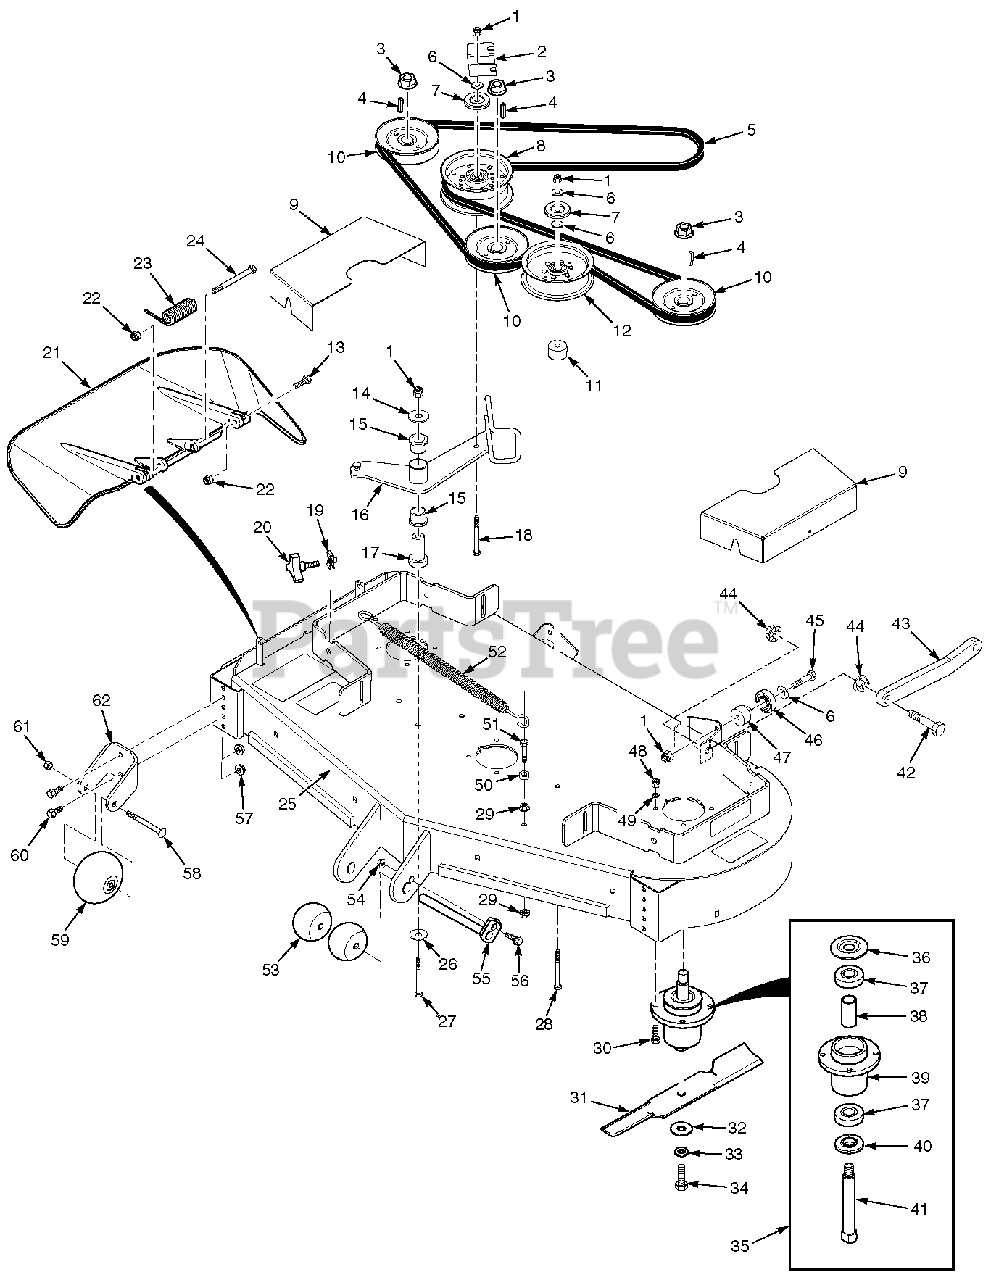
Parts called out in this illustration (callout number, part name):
1	Nut, Elastic Stop 3/8-16
2	Bracket, Belt Guide
3	Nut, 3/4-16 Spiral Lock
4	Key, 1/4 x 1/4 x 1-1/4"
5	Belt, Cutter Deck
6	Flatwasher, 3/8-.391 x .938 x .105
7	Dust Shield
8	Pulley, 5" Idler
9	Belt Cover
10	Pulley, 5.73" OD - 25mm Bore
11	Spacer
12	Pulley, 5" Idler
13	Bolt, Hex Head 5/16-18 x 1-3/4"
14	Flatwasher, 3/8-.406 x 1-1/2"
15	Bearing
16	Idler Arm
17	Pivot, Idler
18	Bolt, Hex Head 3/8-16 x 3-1/4"
19	U-Nut, 3/8-16
20	Knob w/Stud
21	Discharge Chute Assembly
22	Nut, Elastic Stop 5/16-18
23	Spring, Discharge Chute
24	Bolt, Hex Head 5/16-18 x 4-3/4"
25	Cutter Deck w/Decals, SMWZT-52
26	Flatwasher, 3/8-.406 x 2.25" x .188
27	Bolt, Hex Head 3/8-16 x 3-3/4"
28	Bolt, Hex Head 3/8-16 x 3-1/2"
29	Nut, Serrated Flange 3/8-16
30	Bolt, Hex Head 5/16-18 x 1-1/2" Gr.8
31	Cutter Blade, 18"
32	Flatwasher, 5/8-.688 x 1.75 x .134 HD
33	Lockwasher, 1/2 Spring
34	Bolt, Hex Head 5/8-11 x 1-1/2"
35	Spindle Assembly
36	Debris Shield
37	Bearing
38	Spacer
39	Spindle Housing Assembly
40	Protector, Bearing
41	Shaft, Spindle
42	Bolt, Hex Head 1/2-13 x 2"
43	Pusharm
44	Nut, Serrated Flange 1/2-13
45	Bolt, Hex Head 3/8-16 x 2-1/4"
46	Bearing
47	Spacer, Bearing
48	Nut, Elastic Stop 5/16-18
49	Lockwasher, 5/16 Spring
50	Spacer
51	Bolt, Hex Head 3/8-16 x 1-1/2 Gr.8
52	Spring, Idler
53	Wheel, Anti-Scalp
54	Nut, Serrated Flange 5/16-18
55	Shaft Weldment
56	Bolt, Hex Head 5/16-18 x 1"
57	Nut, Serrated Flange 3/8-16
58	Bolt, Carriage 3/8-16 x 4"
59	Wheel, Anti-Scalp
60	Bolt, Hex Head 3/8-16 x 1" Ser. Flg.
61	Nut, Center Lock 3/8-16
62	Bracket, Anti-Scalp
